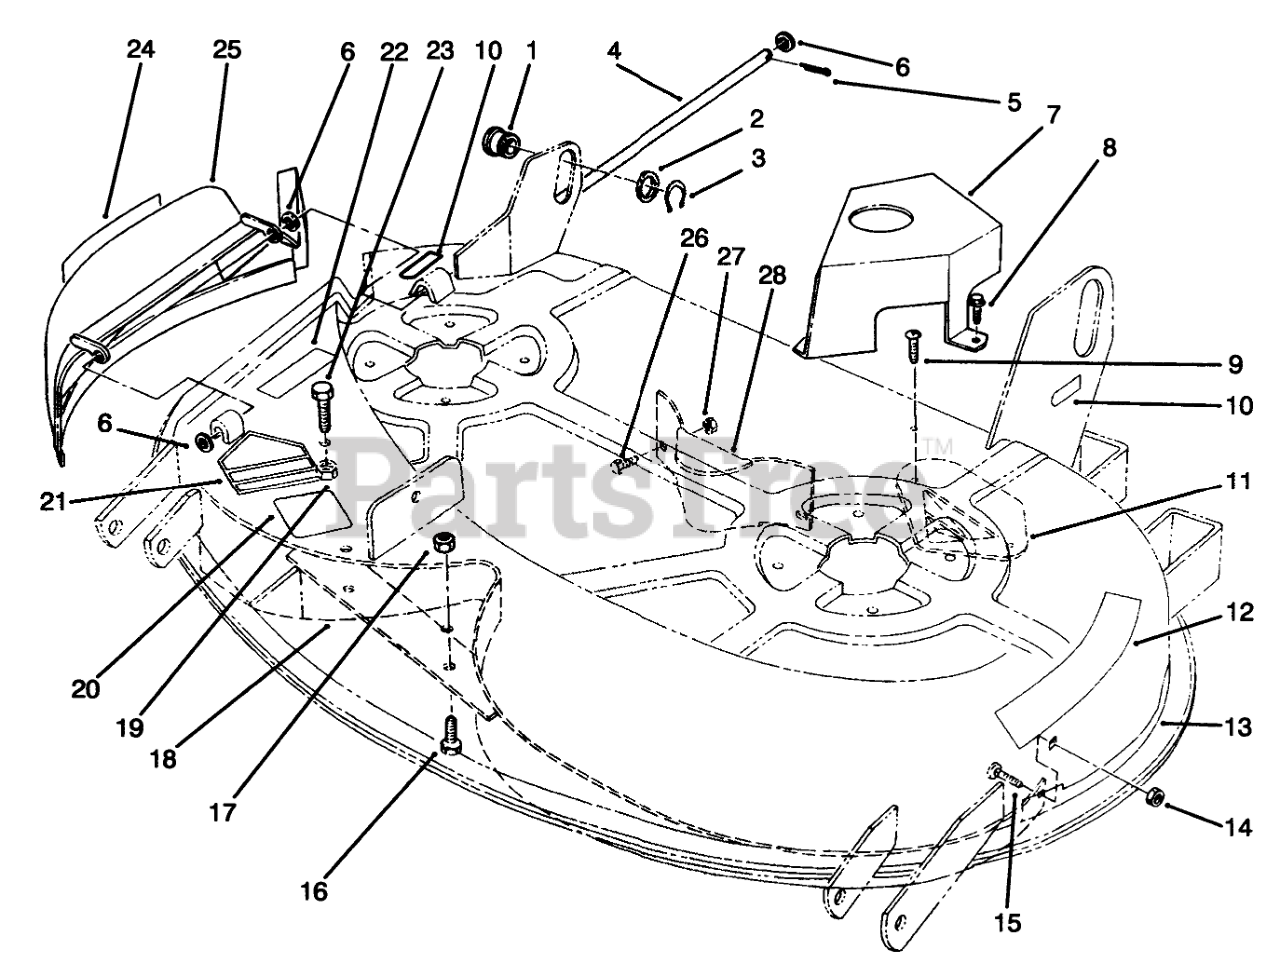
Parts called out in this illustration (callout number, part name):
1	ROLLER-LIFT
2	WASHER
3	RING-RETAINING
5	PIN-COTTER
6	WASHER-PLAIN
7	Cover-Belt
8	SCREW-HWHTF
9	SCREW-PPH
10	Decal-Attach-A-Matic
11	PLATE-KICKER
12	DECAL-DANGER
13	DECAL-RECYCLER DECK 38"
14	NUT-LOCK, NI
15	BOLT-CARR
16	SCREW-HH
17	NUT-LOCK, NI
18	Baffle-38"
19	NUT-LOCK, NI
20	Decal-Routing
21	DECAL-DANGER
22	DECAL-DANGER
23	SCREW-HH
24	DECAL-DANGER, THROWN OBJECT
25	Recycler Chute/Decal Assy. (Incl. Ref. #24)
26	SCREW-HH
27	NUT-LOCK, NI
28	Baffle-Rear
